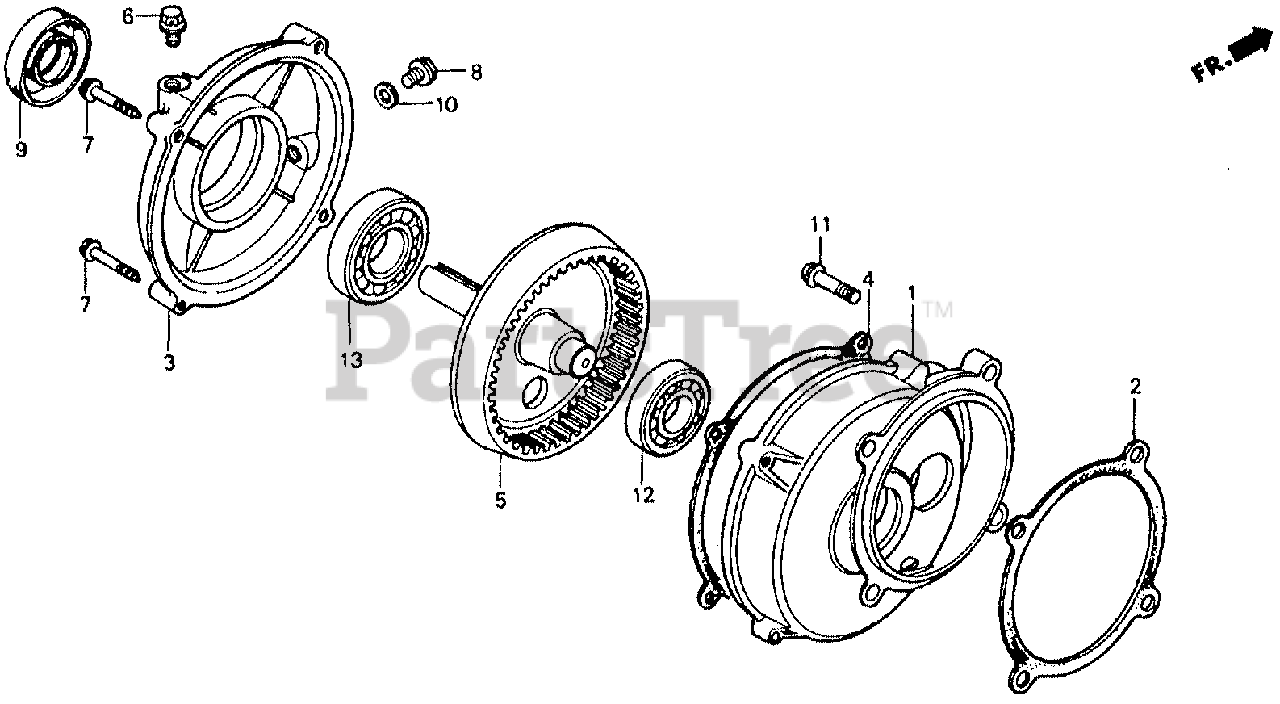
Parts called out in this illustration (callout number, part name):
1	CASE, REDUCTION
2	GASKET, REDUCTION CASE
3	COVER, REDUCTION
4	GASKET, REDUCTION COVER
5	SHAFT, P.T.O.
6	BOLT, BREATHING
7	BOLT, FLANGE (6X32)
7	BOLT, FLANGE (8X35)
8	BOLT, DRAIN PLUG
9	OIL SEAL (30X46X8)
10	WASHER, DRAIN PLUG (12MM)
11	BOLT, FLANGE (8X32)
12	BEARING, RADIAL BALL (6204)
13	BEARING, RADIAL BALL (6206)
